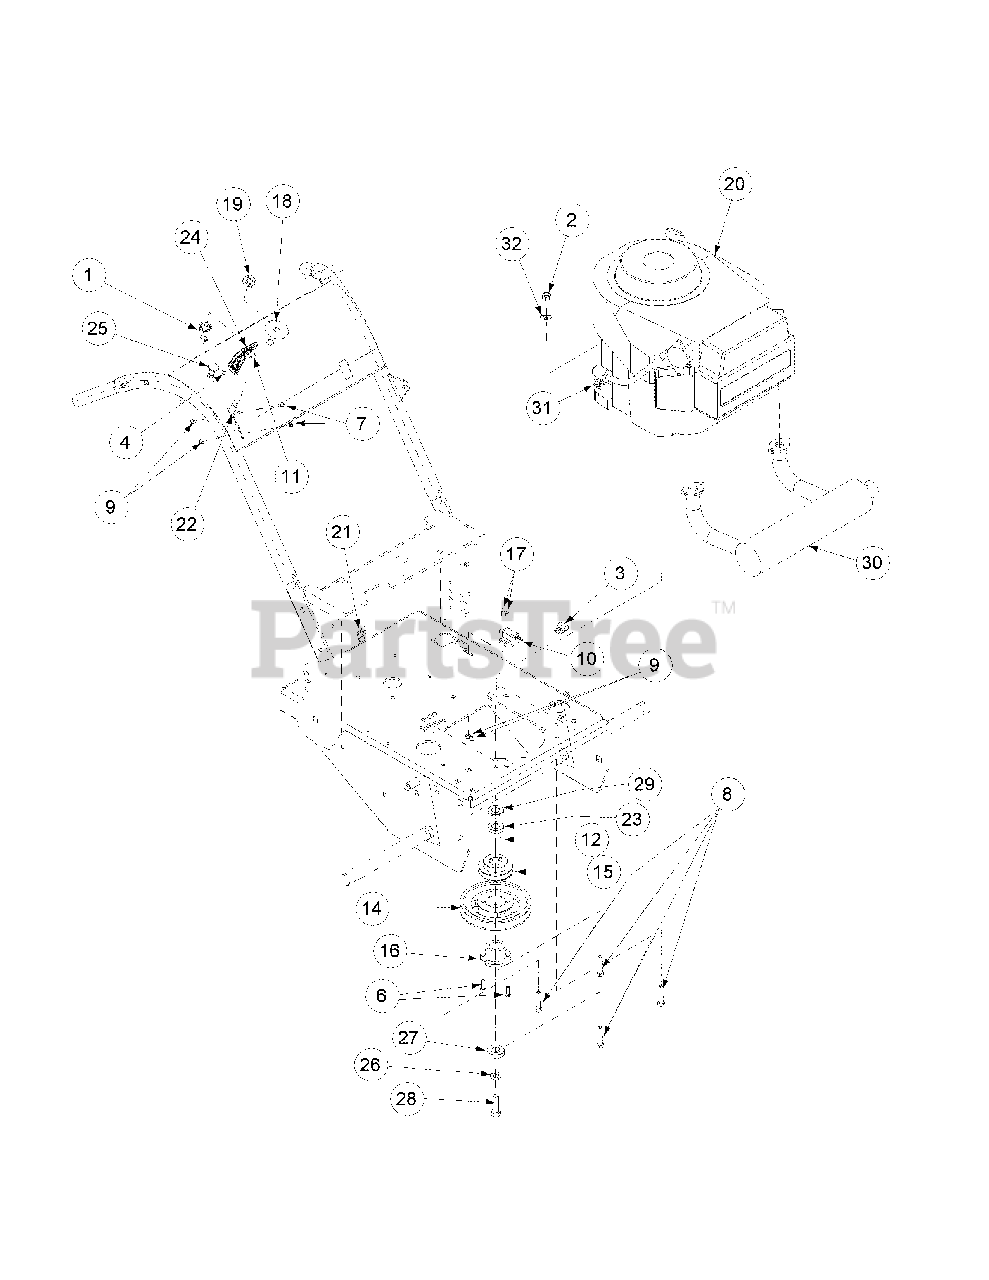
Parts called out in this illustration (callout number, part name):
1	Ignition ON/OFF Switch
2	Lock Nut, Nylon Insert, 5/16-18
3	Support Clamp
4	Nut, 8-32, w/ Star Washer
6	Hex Cap Screw, 1/4-20 x 3/4
7	Screw, Hex Washer, 10-32 x 1/2
8	HHCS, 5/16-18 x 2
9	Lock Nut, Nylon Insert, 10-32
10	Delta Switch
11	Machine Screw, 8-32 x 3.8
12	Key Stick, 1/4 x 1/4 x 2-3/4
14	Deck Pulley
15	Traction Pulley
17	Machine Screw, 10-32 x 5/8
18	Decal, Pull Start Overlay
19	Nut w/cap, 5/8-32 Ignition
20	13 Hp Kawasaki Kai Engine
21	Support Clamp, 3/8 OD
22	Throttle Control Cable
23	Flat Washer
24	Throttle Control Knob
25	Choke Cable
26	Lock Washer, 7/16
27	Clutch Washer
28	Hex Cap Screw, M10 x 1.5, 30mm, GR10.9
29	Spacer, Engine Pulley
31	Hex Nut, 5/16-18
32	Flat Washer, 5/16
